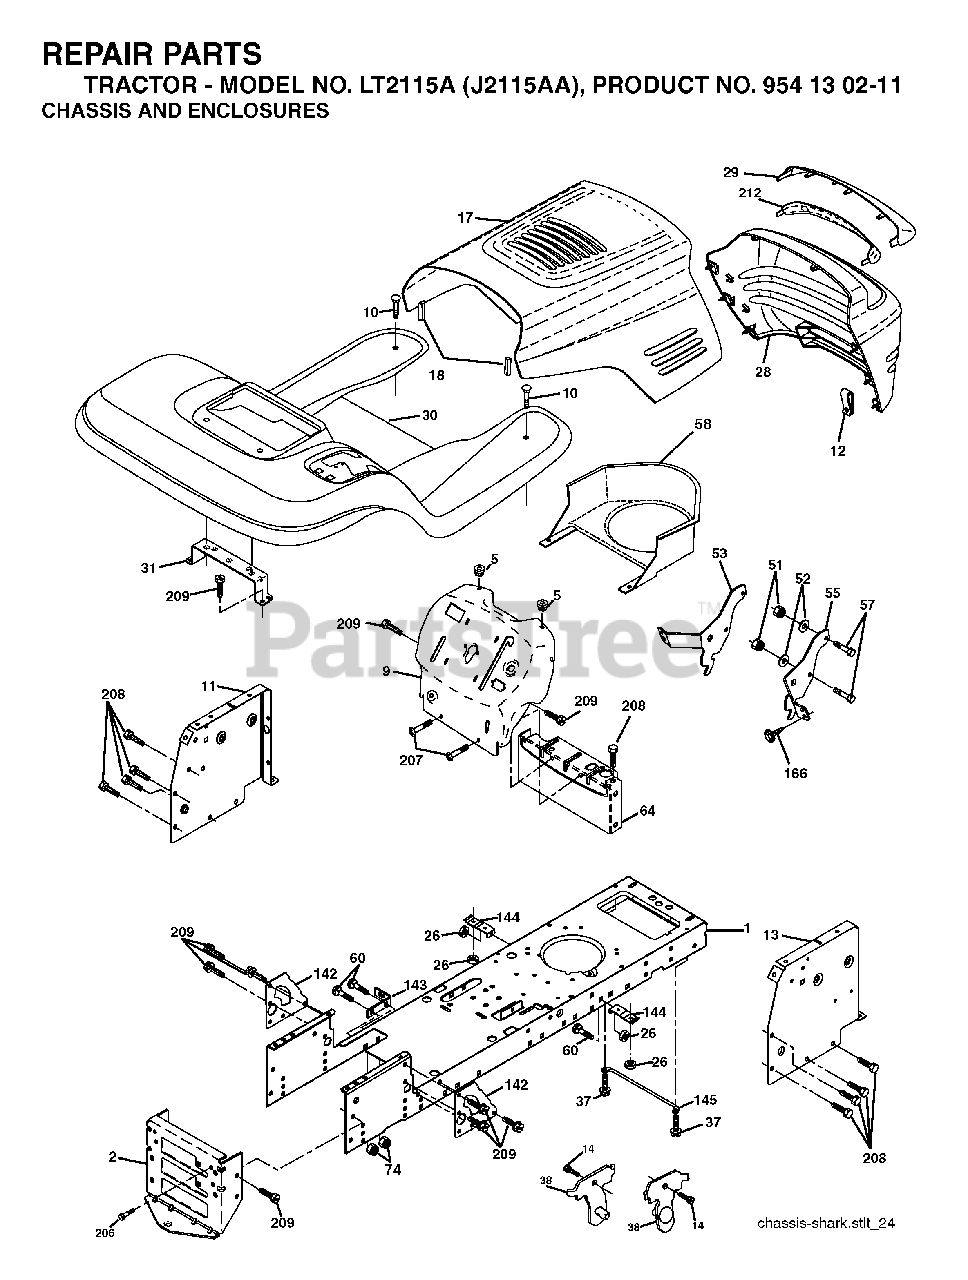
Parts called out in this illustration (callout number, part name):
1	CHASSIS STAMPING
2	DRAWBAR, 12GA
5	BUMPER.RUBBER.HOOD
10	BOLT D
11	PANEL.DASH.LH.LTX
13	PANEL DASH RH
18	BUMPER.HOOD.LARGE.1.75"
26	NUT
38	BRACKET.ASM.PIVOT.MOWER.REAR
51	LOCKNUT
57	BOLT
64	DASH LOWER
74	LOCKNUT
142	PLATE REINFORCEMENT
143	BRACKET, SWAYBAR CHASSIS
144	BRKT, FOOT REST
145	ROD PIVOT CHASSIS/HOOD
166	SCREW
206	SHOULDER BOLT 5/16-18TT
207	SCREW, 5/16-18 X 1/2
208	SCREW 3/8-16X1/2
209	SCREW, 3/8-16X3/4
